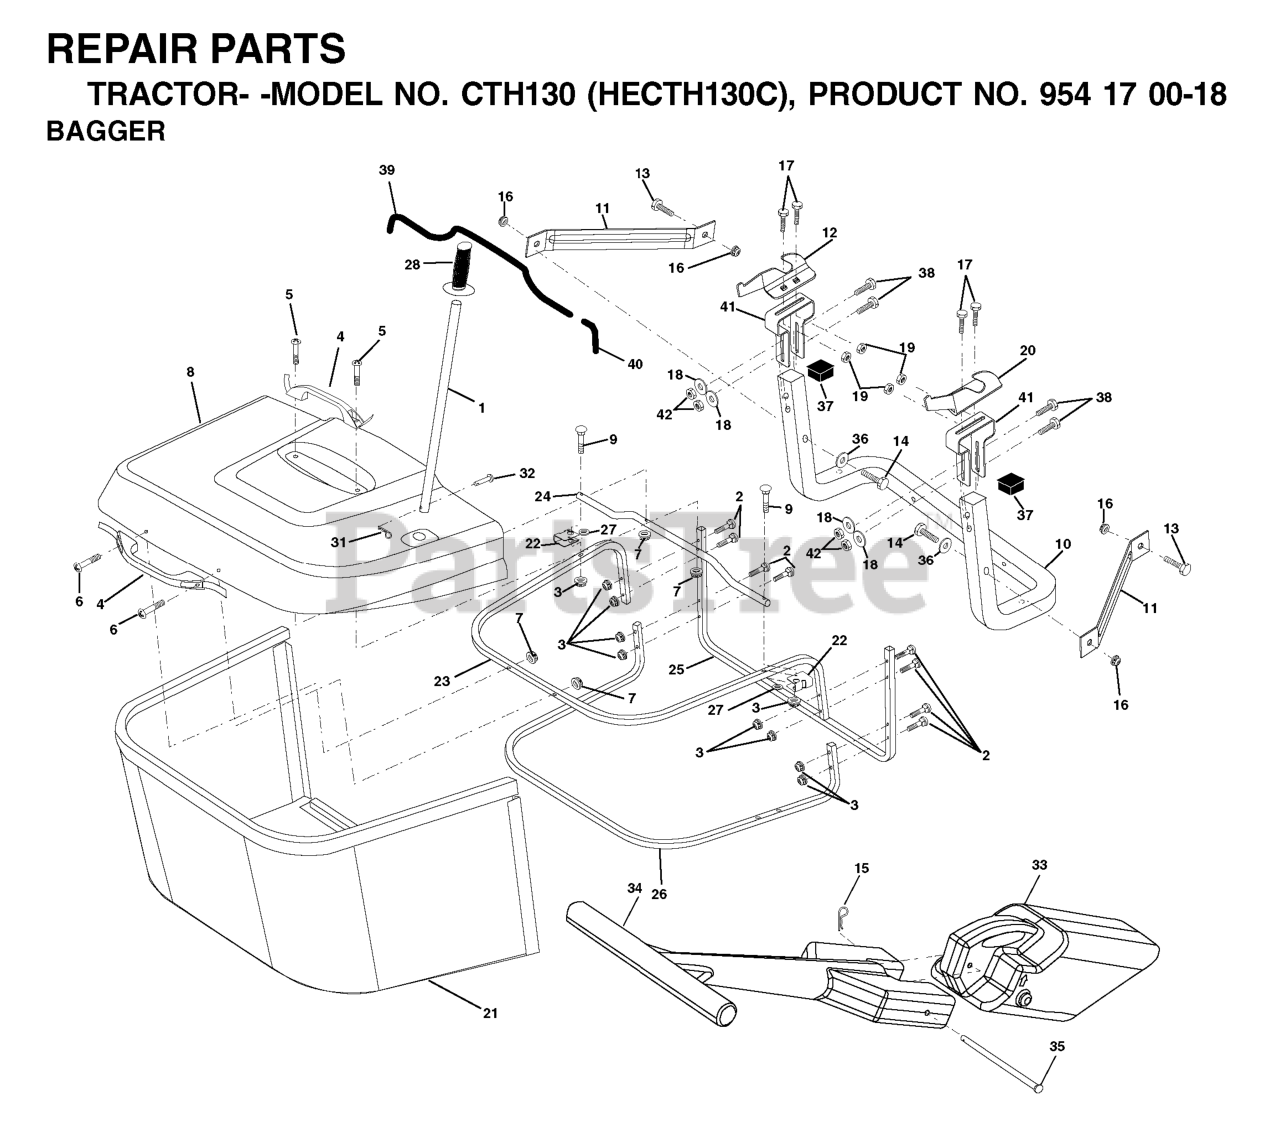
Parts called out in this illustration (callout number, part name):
1	TUBE HANDLE BAGGER
2	Bolt Carriage 1/4-20 x 2.0 Gr.5
3	NUT T
4	HANDLE.BAGGER.W/LVRS.BLK.CRD
5	SCREW.PAN.HEAD
6	REPL BY 532 75 00-29
8	COVER
9	Bolt Carriage 1/4-20 x 2.25d x Gr.5
10	TUBE
11	BRACKET.SUPPORT.UPPER.BAG.CRD
14	Bolt Hex 3/8-16 x 2-1/2 Gr. 5
15	RETAINER-SPRNG RB
16	NUT LOCK FLG 3/8-16 UNC
17	RP BOLT 5/16-18 X3/4 ZN/YEL GR
18	WASHER M
19	NUT LOCK HEX FLANGE 5/16-18
20	BRACKET
21	BAG
22	BRKT.SIDE.BAG.CRD
23	TUBE.UPPER.BAG.CRD
24	TUBE.PIVOT.BAG.CRD.BLACK
26	TUBE.LOWER.BAG.CRD
28	Grip Handle Black
31	RETAINER M
32	RIVET,DRILLED
33	PLUG.MULCHER.92 CRD
34	HANDLE.MULCHER.92.CRD (2 2)
36	WASHER
37	Plug Support Bagger CRD
38	BOLT.5/16-18X2.5
39	TRIM
40	TRIM
41	BRKT.VERT.ADJ.BAGGER.CRD
42	NUT.71038.31-18.HEX.NYLOCK
